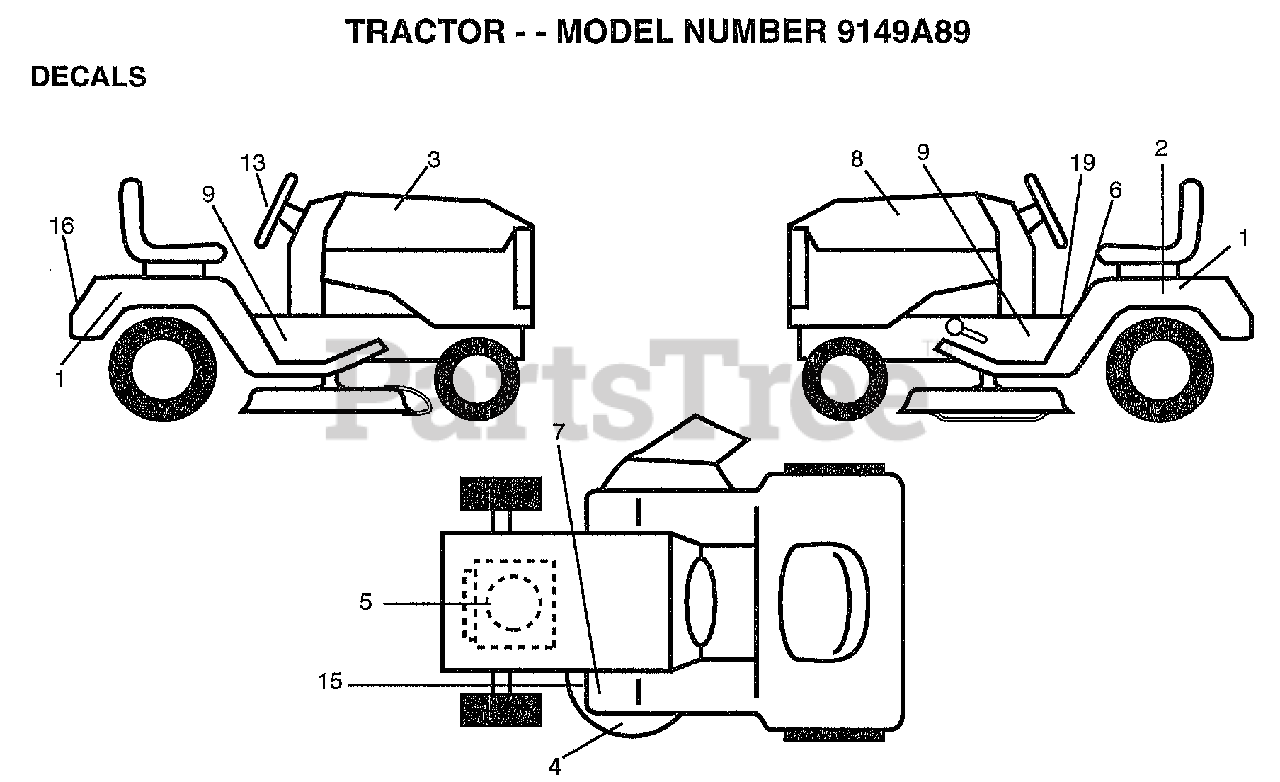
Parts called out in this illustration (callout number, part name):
1	DECAL.FENDER.WIZ
2	DECAL.BATRY.3-3908
3	DECAL.HOOD.RH
4	DECAL DECK WIZ +
5	DECAL, ENGINE
6	"DECAL DANGER,FEND"
8	DECAL.HOOD.LH
9	"DECAL.CHASSIS.42"""
13	DECAL.INS.STRG.WL
15	"DECAL-SCHEM,BELT"
19	"DECAL INST,SADDLE"
